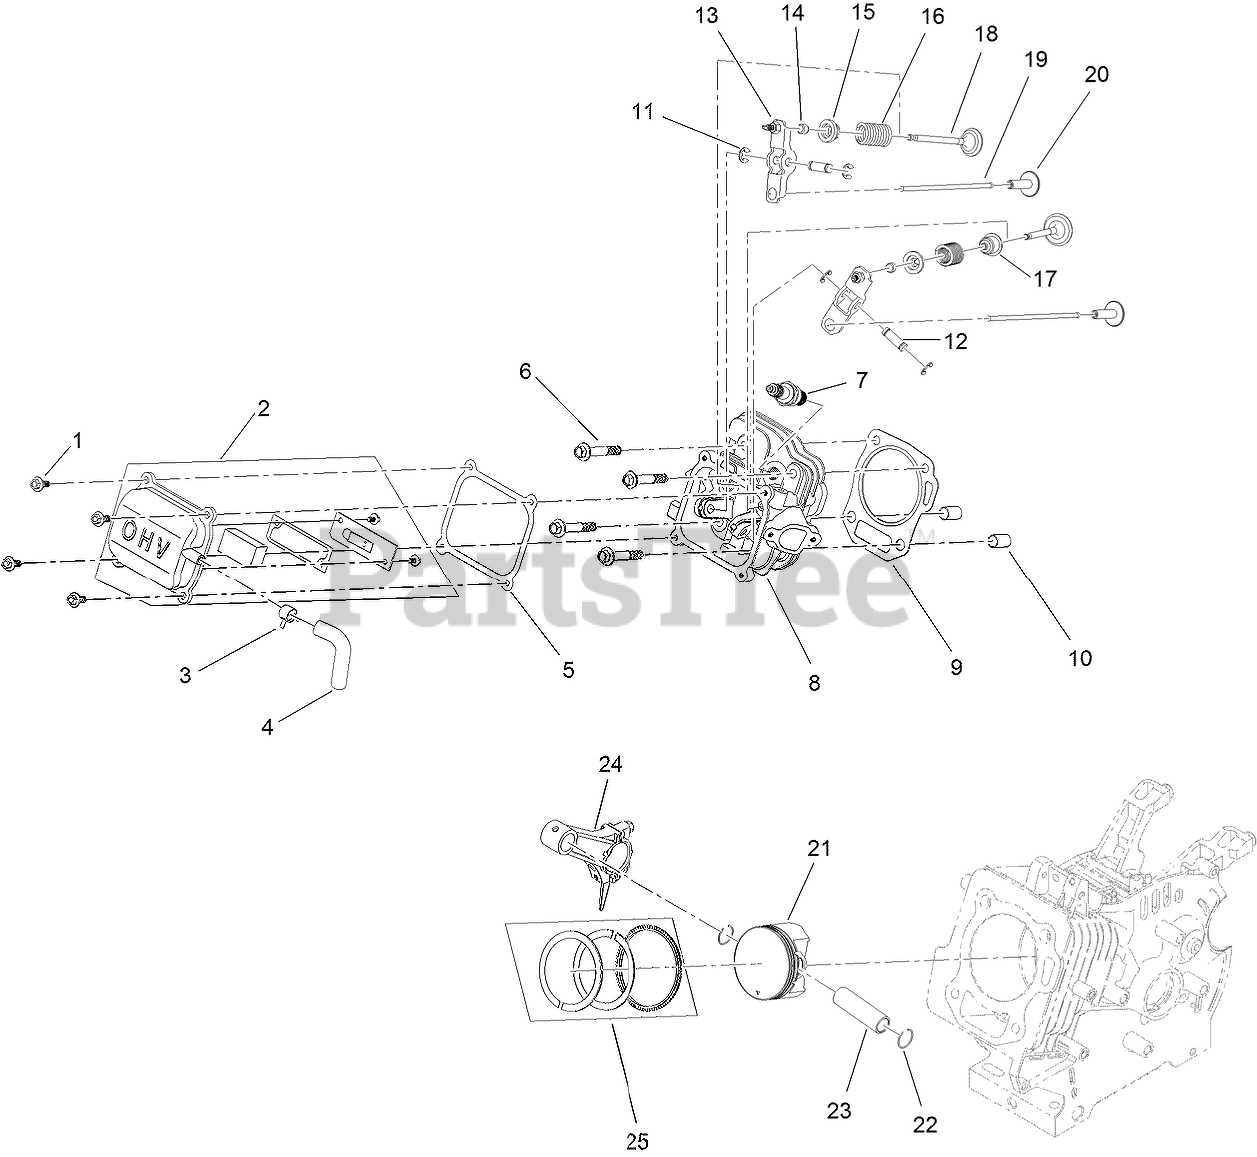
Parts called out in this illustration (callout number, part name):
1	SCREW-HHF
2	VALVE COVER ASM
3	CLAMP-HOSE
4	TUBE-BREATHER
5	GASKET-COVER, VALVE
6	SCREW-FLANGE
7	SPARK PLUG
8	HEAD-CYLINDER
9	GASKET-HEAD
10	PIN-DOWEL
11	E-CLIP
12	PIN-ARM, ROCKER
13	ROCKER ARM ASM
14	ROTATOR-VALVE
15	RETAINER-SPRING, VALVE
16	SPRING-VALVE
17	SEAL-STEM, VALVE
18	SET-VALVE
19	ROD-PUSH
20	TAPPET-VALVE
21	PISTON
22	CLIP-PIN, PISTON
23	PIN-PISTON
24	CONNECTING ROD ASM
25	SET-RING, PISTON
